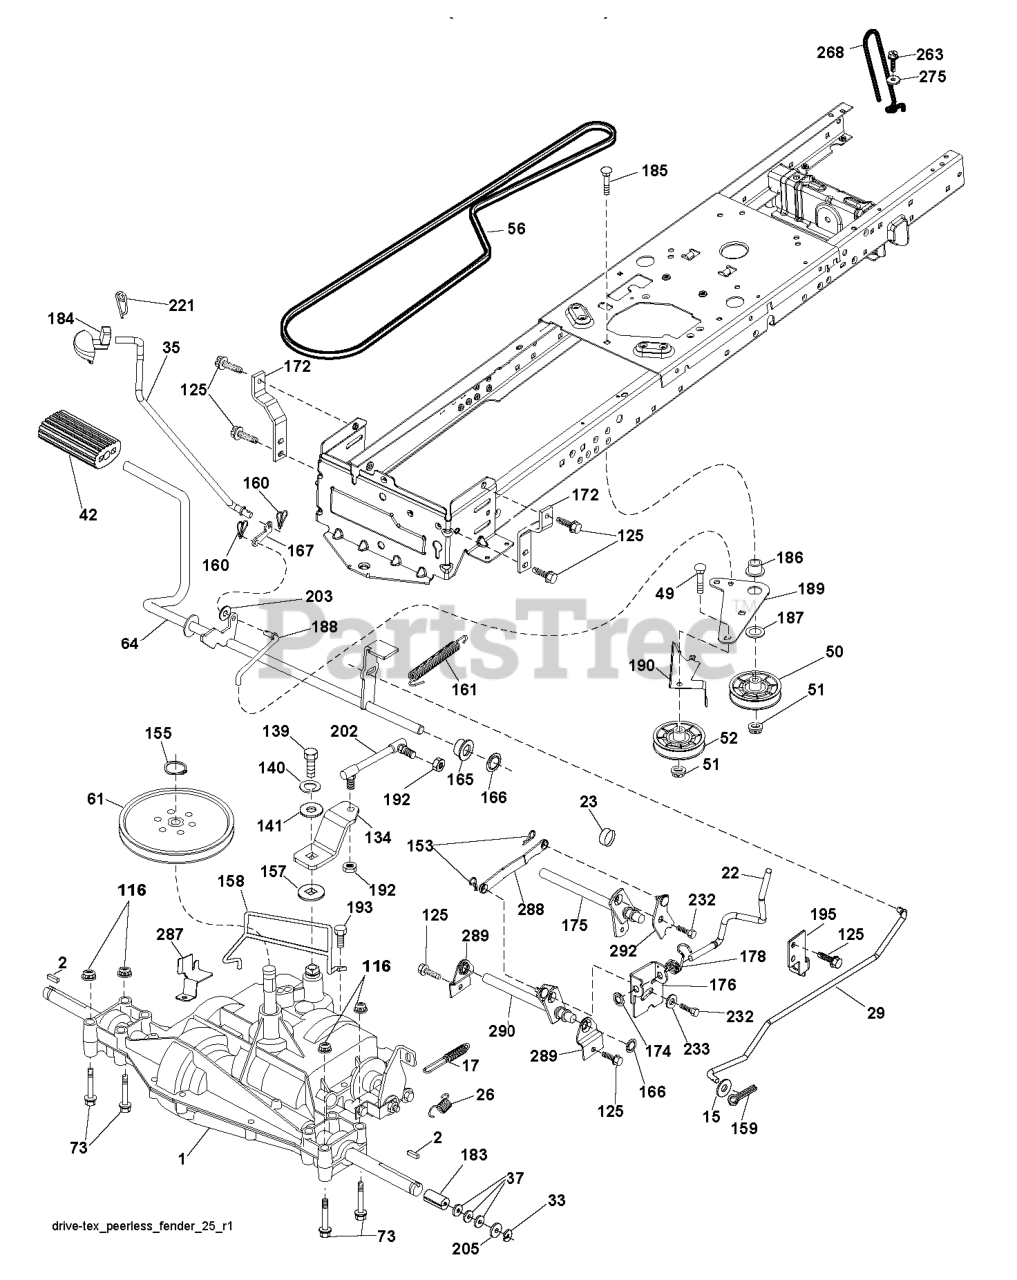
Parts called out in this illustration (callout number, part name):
2	SQUARE KEY
15	WASHER
17	SPRING.BRAKE.PEERLESS.TEX
22	SHIFTER.ASM.HANDLE.SRD
23	KNOB.DUCKHEAD.1/2
26	SPRING.BRAKE.RTN.GR.DR
29	ROD.BRAKE.PEERLESS
35	ROD.CNTRL.PARK.PREDATOR.LT.TEX
42	PEDAL COVER T
50	IDLER.FLAT.910.OFFSET
51	NUT LOCK FLG 3/8-16 UNC
52	IDLER.V-GROOVE.910.OFFSET
56	BELT, V GROUND DRIVE 95 25
61	PULLEY
64	SHAFT.ASM.PEDAL.BRAKE.
73	BOLT HEX 5/16-18 GR 5
116	NUT LOCK HEX FLANGE 5/16-18
125	SCREW
139	BOLT 1/4-28X3/4
140	LOCKWASHER
153	RETAINER M
155	RETAINING RING LT
157	WASH-SHFT PLT LT
158	KEEPER.PMS.18/20.D4365
159	COTTER PIN
160	RETAINER CLIP
161	SPRING, RETURN LT
165	BUSHING.SHAFT.BRAKE.HAND
166	NUT.PUSH.625
167	LATCH.BRAKE.SPRING
172	STRAP.TRQ.LH.GEAR.DRIV
174	NUT.PUSH.500.2006
175	SHAFT ASM SHIFT
176	ARM.CLEVIS.ROD.SHIFT
178	SPRING.TORSION.LIFT.HANDLE
183	SPACER AXLE
184	HANDLE PARKING BRAKE
186	SPACER.RETAINER
187	WASHER 12/32X2X10GA
188	RP.LINK.CLUTCH.GROUND.DRIVE
189	BELLCRANK.GROUND.DRIVE.TEX.
190	KEEPER.BELLCRANK.DRIVE
192	NUT LOCK CENTER 1/4 -28 FNTHD
193	SCREW 5/16"
195	BRKT.ROD.BRAKE.PEERLES
202	LINK.SHIFT.PMST.18" (SPG1286)
203	WASHER
221	RETAINER.SPRING.CLIP.H
232	BOLT FIN HEX 7/16-14 X 1
233	WASHER SERRATED
263	SCREW, 3/8-16X3/4
268	GUARD MUFFLER
275	WASHER
287	KEEPER.PULLEY.T/A.7.04
288	LINK.SHIFT.SLAVE.SRD
289	BRACKET.SUPPORT.SHIFT.OUTER
290	SHAFT.ASM.SHIFT.REAR.SRD
292	PLATE.ASM.SHIFT.FWD.SRD
